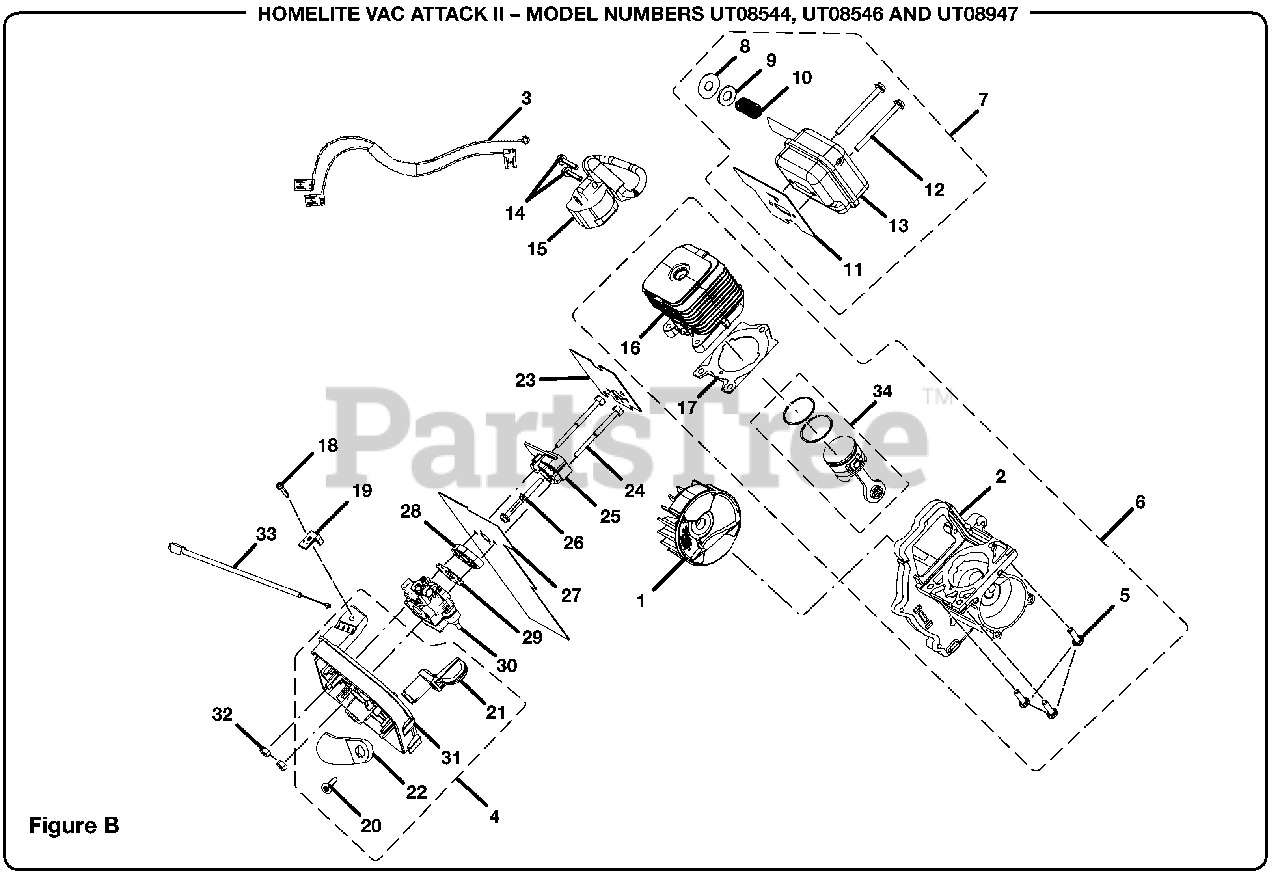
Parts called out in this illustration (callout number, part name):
1	Flywheel Assembly
2	Crankcase Assembly
3	Ignition & Switch Harness
4	Air Box Base Assembly
5	Screw (M5 X 20 mm)
6	Short Block Assembly
7	Muffler Assembly
8	Insulating Washer
9	Flat Washer
10	Compression Spring
11	Muffler Gasket
12	Screw (10-24 Hex. Hd.)
14	Screw (8-32 X 1 in.)
15	Ignition Module
16	Cylinder
17	Cylinder Gasket
18	Screw (M4 X 16 mm)
19	Throttle Cable Clip
20	Screw (M4)
21	Choke Lever
22	Choke Plate
23	Heat Dam Gasket
24	Carburetor Mounting Bolt
25	Heat Dam
26	Screw (10-24 X 1-1/6 in. Pan Hd.)
27	Carburetor Gasket
28	Spacer
29	Gasket
30	Carburetor
31	Air Filter Box
32	Hex Nut (10-24)
33	Throttle Cable
34	Piston and Rod Assembly
